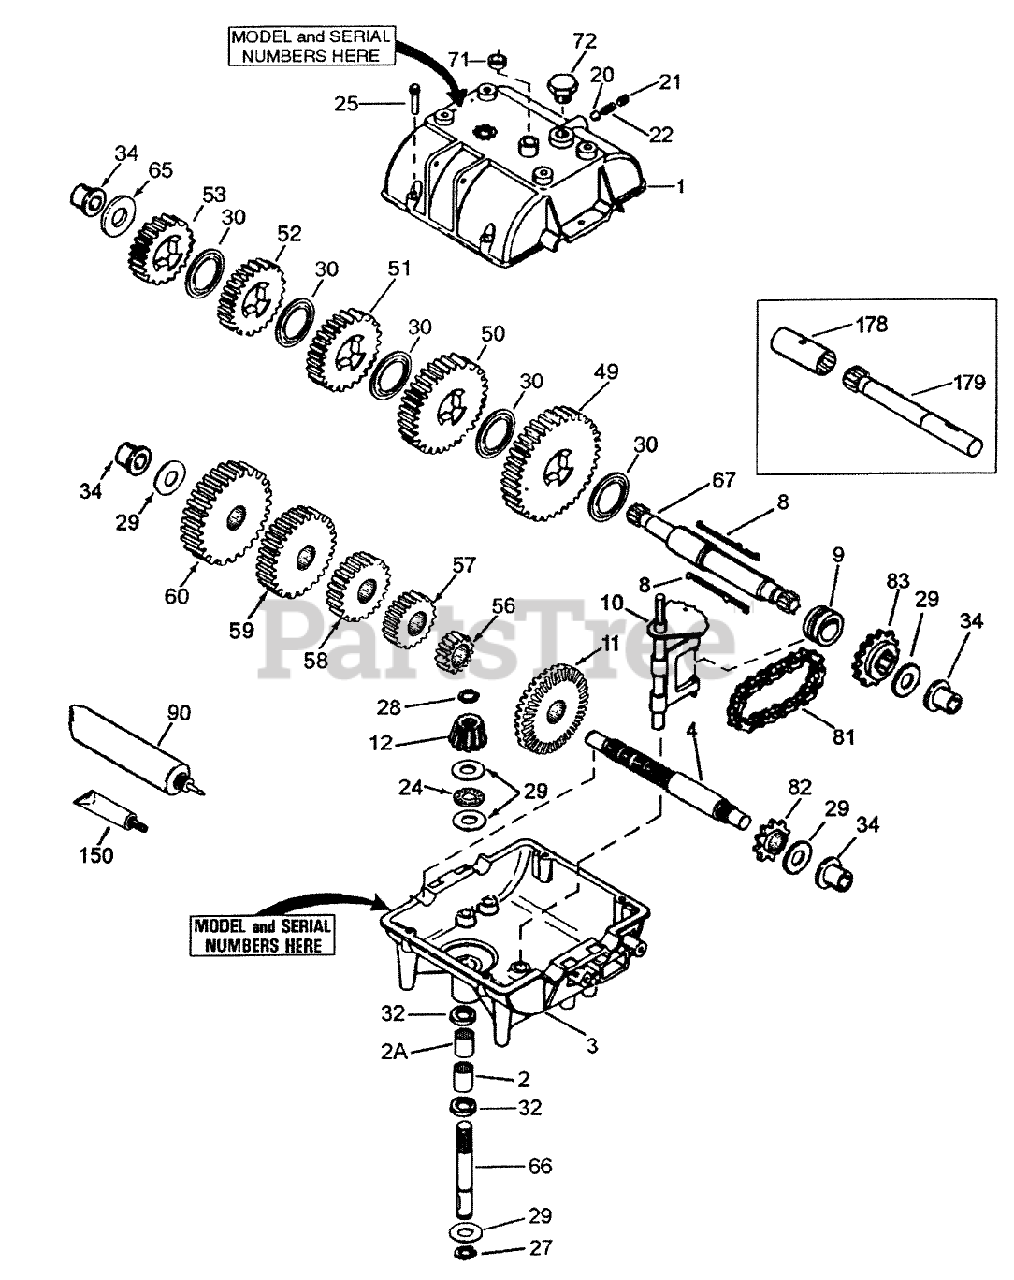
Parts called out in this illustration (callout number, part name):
1	Cover-Transmission
2	Bearing-Needle
2A	Bearing-Needle
3	Case-Transmission
4	Countershaft
9	Collar-Shift
10	Shift Rod Fork
11	Gear-Bevel, 42 teeth
12	Bevel Pinion (14 Teeth-Steel)
20	Ball-Steel
21	Screw-Set
22	Spring
24	Bearing-Thrust
25	Screw
27	Ring-Snap
28	Ring-Retainer
29	Washer
30	Washer
32	O Ring
34	Bushing-Flange
49	Gear-Spur, 37 Teeth
50	Gear-Spur, 35 Teeth
51	Spur Gear (32 Teeth-Steel)
52	Gear-Spur, 30 Teeth
53	Gear-Spur, 25 Teeth
56	Gear-Spur, 12 Teeth
57	Gear-Spur, 15 Teeth
58	Spur Gear (18 Teeth-Steel)
59	Gear-Spur, 20 Teeth
60	Gear-Spur, 25 Teeth
65	Washer
66	Shaft-Input
67	Shifter and Brake Shaft
71	Cut Seal-Square
81	Chain-Roller #41
82	Sprocket-9 Teeth
83	Sprocket-18 Teeth
90	Grease 32 Oz
150	Gasket Eliminator
178	Coupling (Optional)
179	Connector Shaft(Optional)
